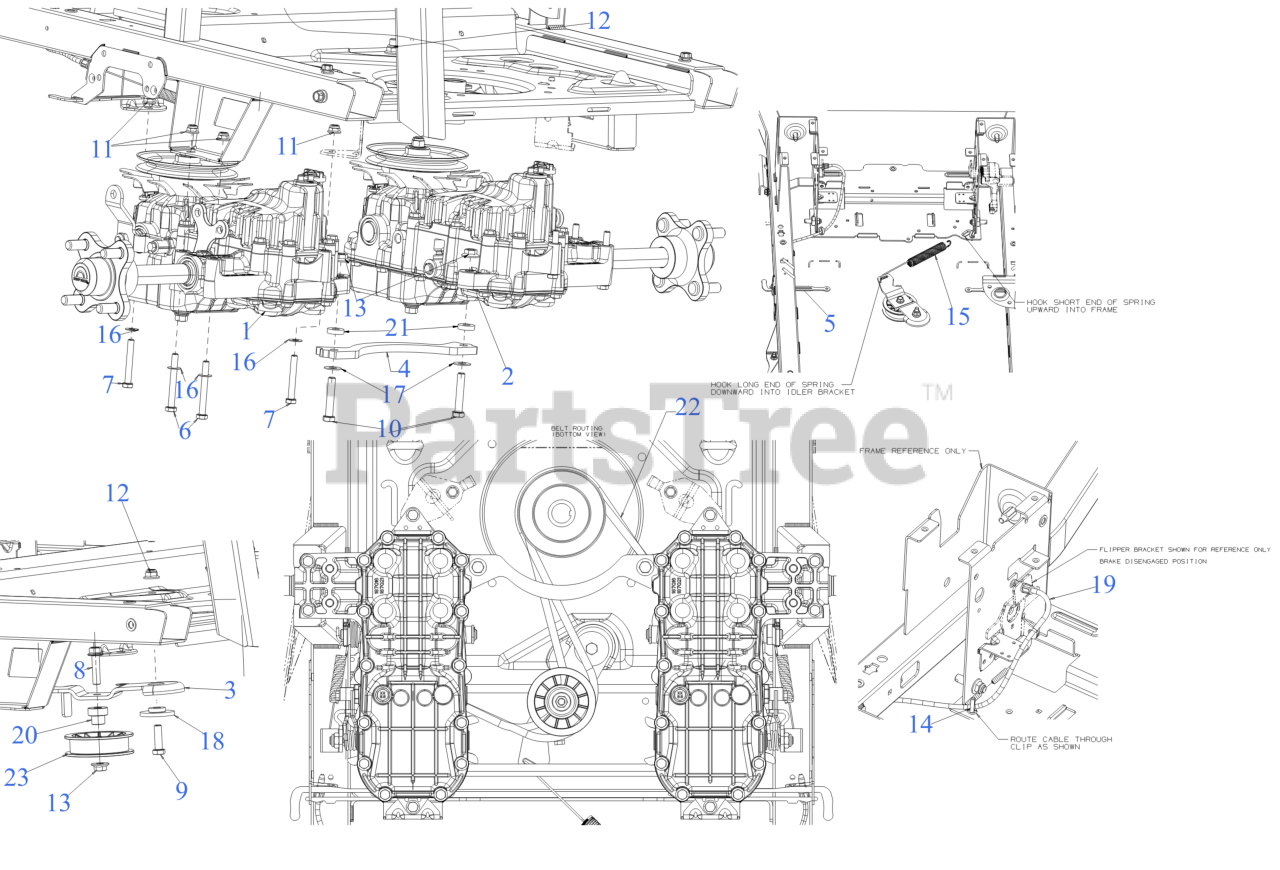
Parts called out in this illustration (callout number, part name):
1	HYDRO TRANSMISSION (LH)
2	HYDRO TRANSMISSION (RH)
3	HYDRO DRIVE IDLER BRACKET
4	TRANSMISSION BRACKET
5	TRANSMISSION BYPASS PLATE
6	HEX SCREW 5/16-18 x 2.75
7	HEX SCREW 5/16-18 x 2.25 GR5
8	HEX HEAD BOLT (3/8-16:1.50 GR8)
9	SCREW 3/8-16 x 1.25 GR5
10	SCREW 3/8-16 x 2.0 GR 8
11	FLANGE LOCK NUT 5/16-18
13	FLANGE LOCK NUT
14	CABLE RETAINER CLIP
15	EXTENSION SPRING .75 DIA X 10.27
16	FLAT WASHER
17	FLAT WASHER .401X.88
18	SHOULDER SPACER
19	PARK BRAKE CABLE
20	SHOULDER SPACER
22	TRANSMISSION DRIVE BELT A x 67
23	FLAT IDLER PULLEY 3.00 OD
